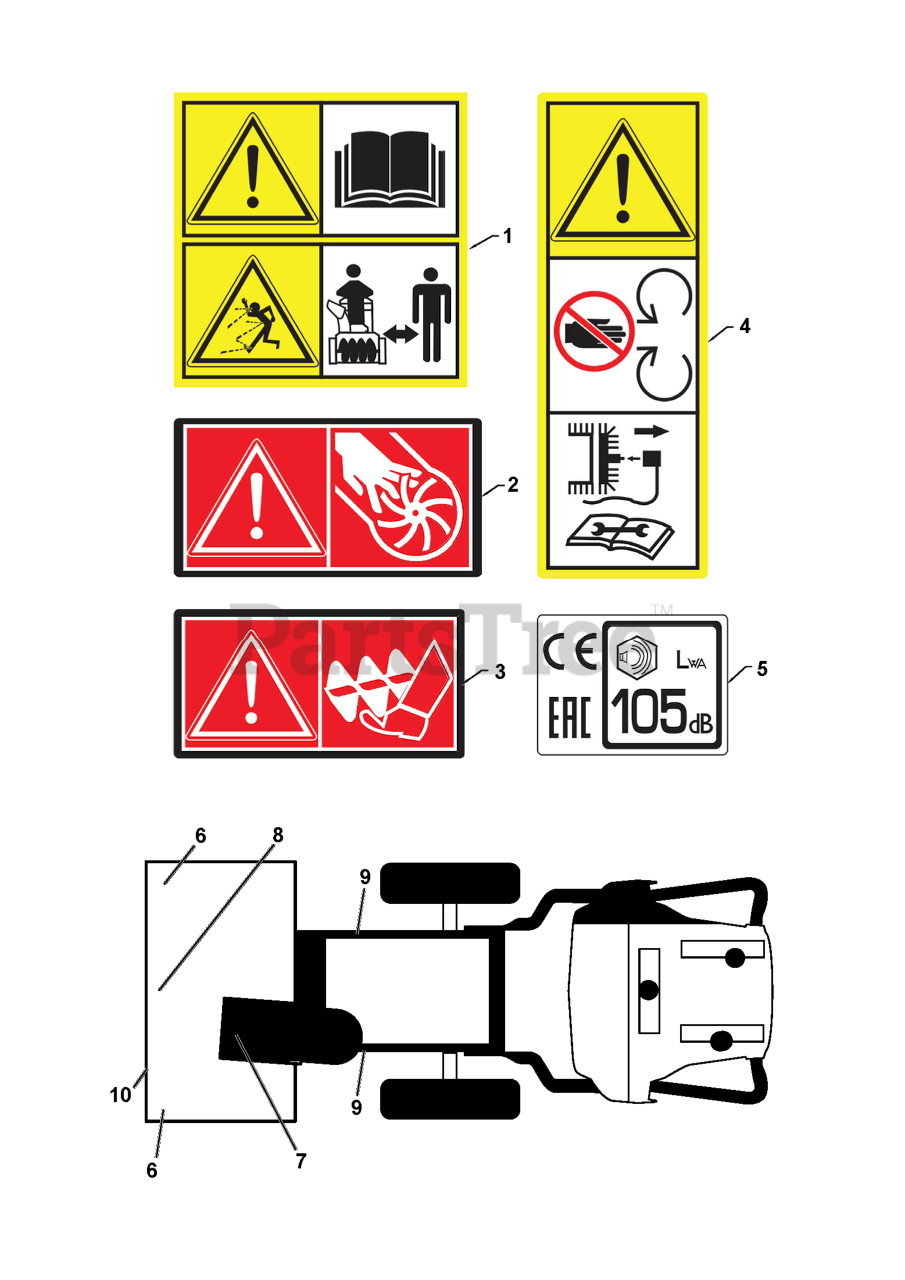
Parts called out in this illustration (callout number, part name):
1	DECAL.AUGER."
2	DECAL.CHUTE.SAFETY.EU/SC.17
3	DECAL.AUGER.SAFETY.
4	DECAL.BELT.GUARD.
5	DECAL.NOISE.LEV.105/CE.EAC.UKR
6	DECAL.AUGER.SAFETY.
7	DECAL.CHUTE.SAFETY.EU/SC.17
8	DECAL.AUGER."
9	DECAL.BELT.GUARD.
10	DECAL SNOW BUCKET TRIM GRAPHIC
